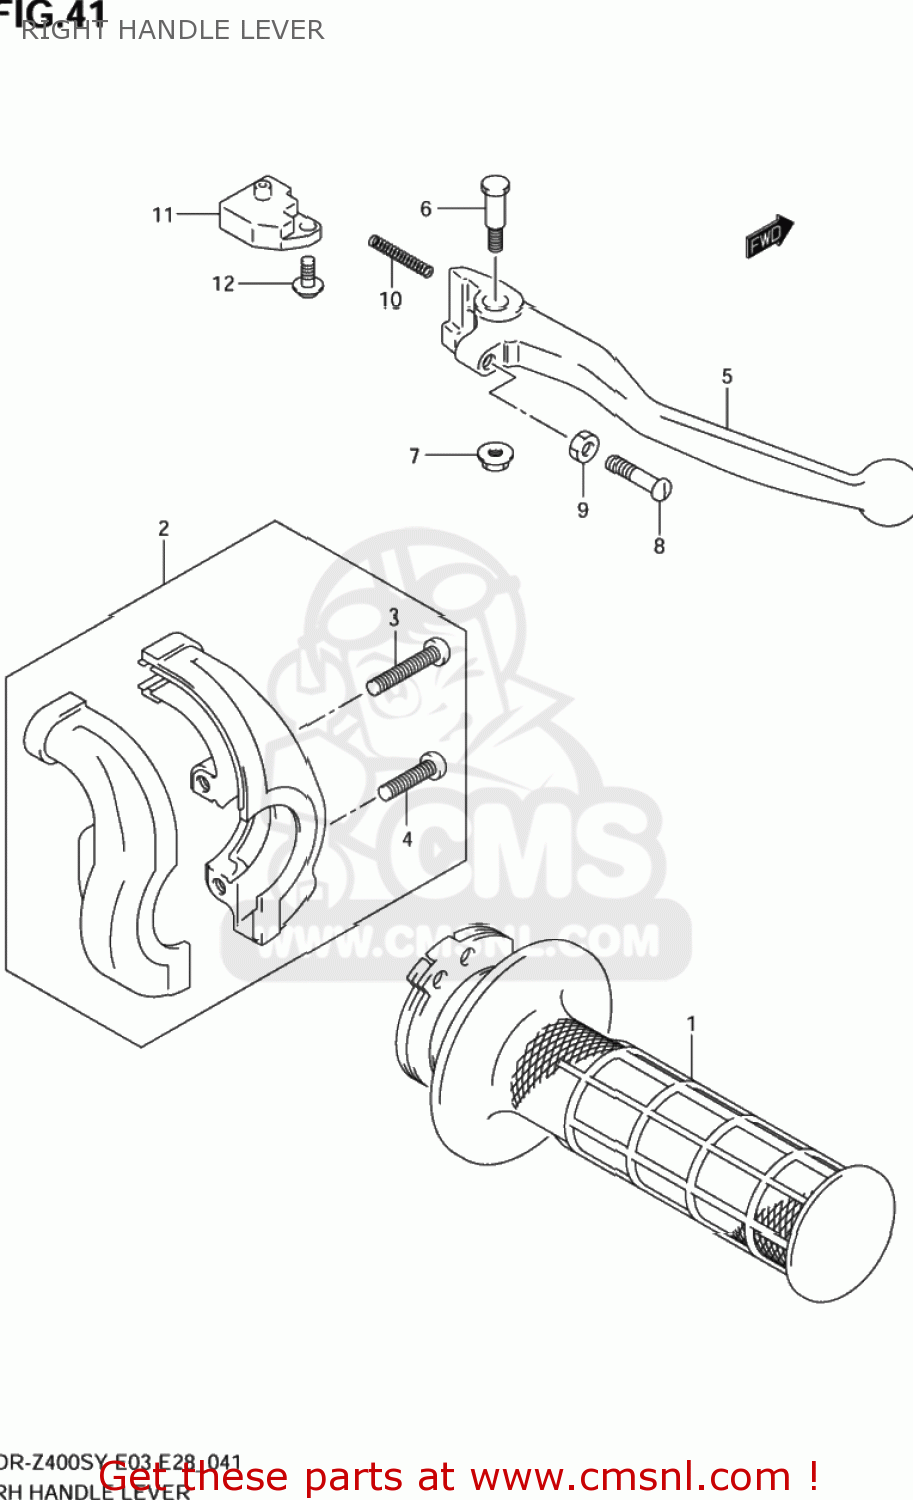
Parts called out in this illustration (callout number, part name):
1	GRIP,THROTTLE
2	CASE ASSY,THROTTLE
3	SCREW(5X25)
4	SCREW
5	LEVER,BRAKE
6	BOLT,BRAKE LEVER
7	NUT 6MM
8	BOLT,ADJUST
9	NUT
10	SPRING,RETURN
11	SWITCH ASSEMBLY,STOP
12	SCREW
